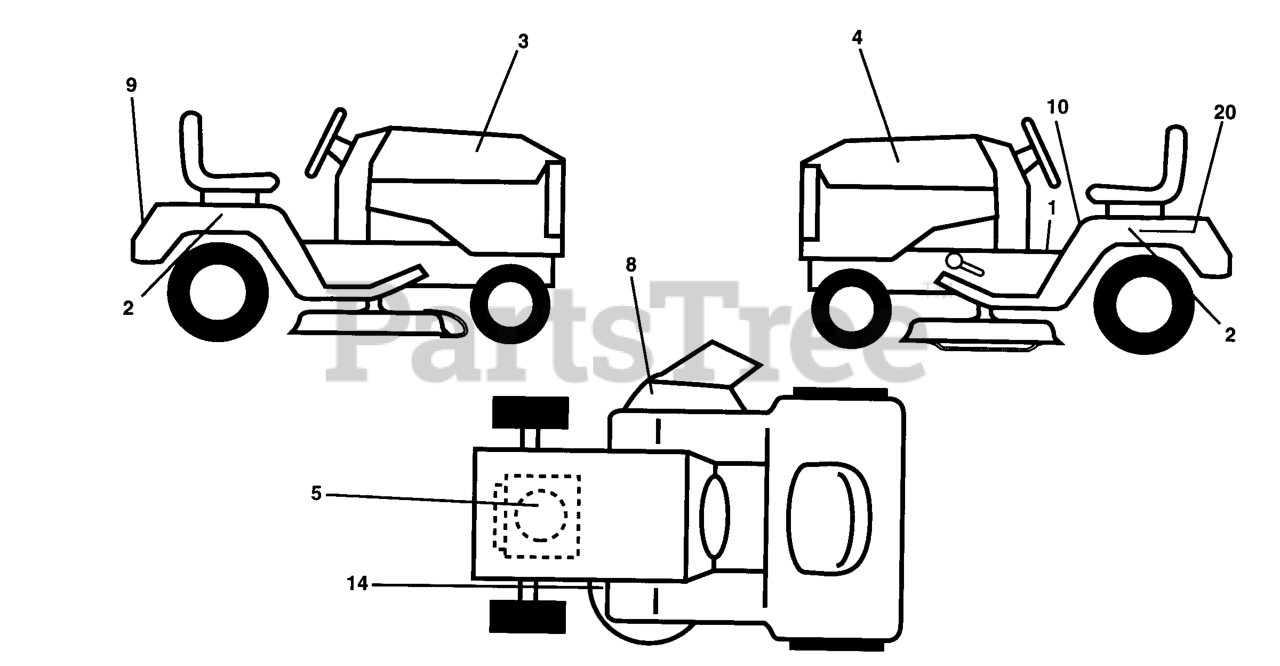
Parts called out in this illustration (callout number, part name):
3	DECAL, HOOD LH LTH120
4	DECAL, HOOD RH LTH120
5	DECAL HP ENGINE
8	DECAL WARNING (ENGLISH/FRENCH)
9	DECAL FENDER HUSQ
10	DECAL FENDER DANGER
14	DECAL V-BELT SCHEMATIC
20	DECAL, BATTERY DANGER
